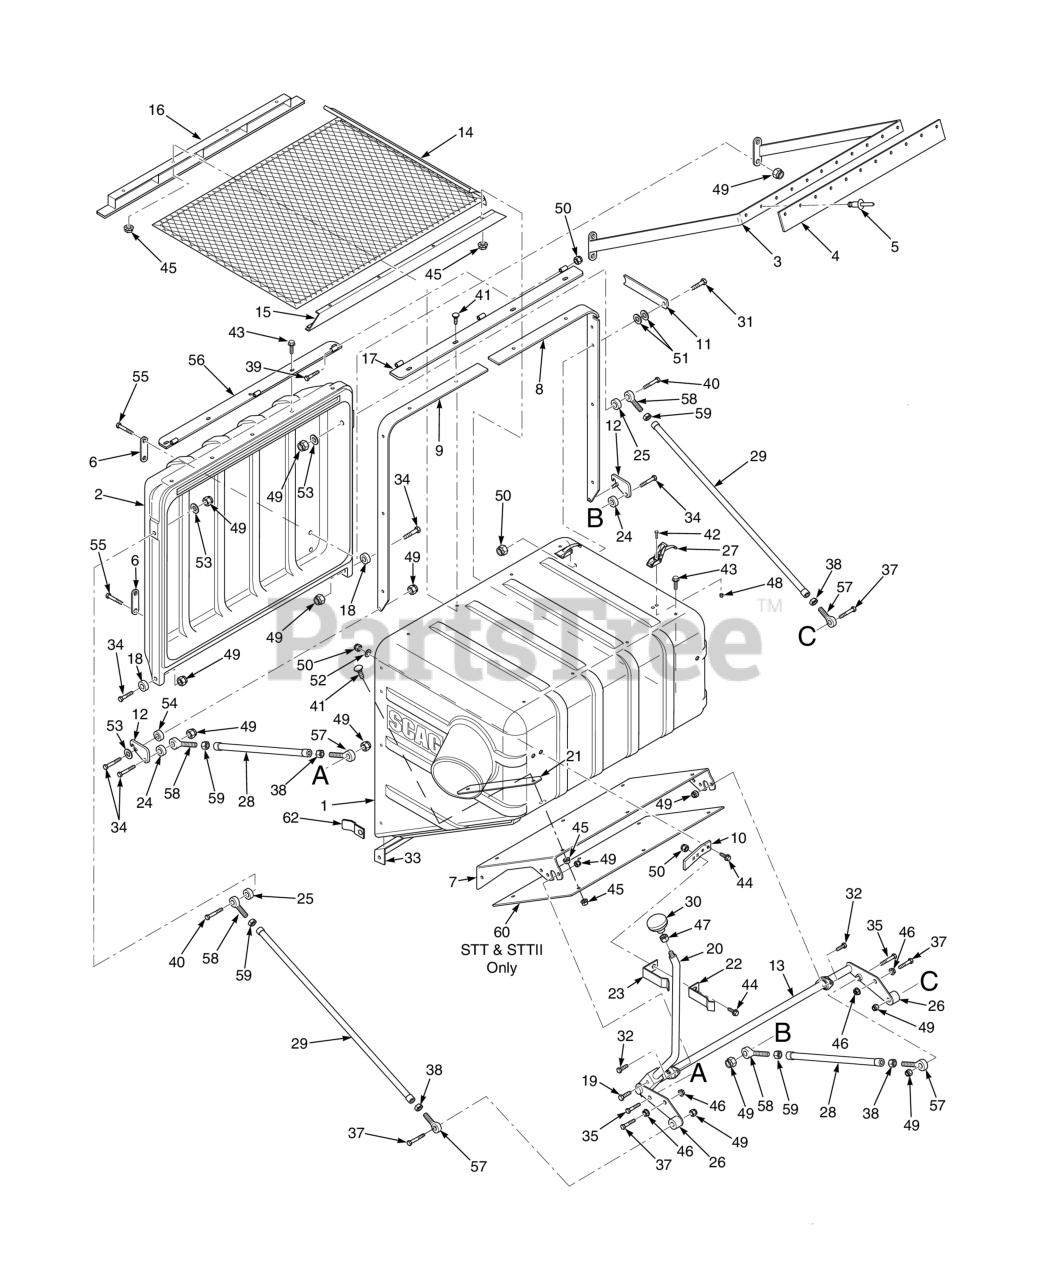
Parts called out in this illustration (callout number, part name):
1	Hopper, GC-STT-CS
2	Door, GC-CS
3	Sweeper Weldment, GC-CS
4	Pad, Rubber
5	Pop Rivet, 3/16 x .652"
6	Plate, Stiffener
7	Support Frame, Hopper
8	Hinge Bracket, L.H.
9	Hinge Bracket, R.H.
10	Mounting Bracket, Dump Handle Latch
11	Latch, Door Prop
12	Plate, Latch
13	Bellcrank Weldment, Upper
14	Debris Screen Weldment
15	Screen Support Weldment, Rear
16	Screen Support Weldment, Front
17	Hinge Weldment, Hopper
18	Spacer, Idler Bearing
19	Bolt, Hex Head 5/16-18 x 1-1/2" - Front
20	Rod, Dump Lever GC-SCZ-CS
21	Retainer Strip, Hopper
22	Latch, Dump Rod Inner
23	Latch, Dump Rod Outer
24	SPACER, IDLER
25	SPACER, J PULL ROD
26	SPACER, J-PULL ROD
27	LATCH, HOOD
28	Linkage Assembly, Lower
29	Linkage Assembly, Upper
30	Knob, Cutter Deck Release
31	Bolt, 5/16 - 18 x 1 - 1/4" Hex Head
32	Bolt, Hex Head, 3/8-16 x 3/4"
33	Bracket, Lower Stiffener
34	Bolt, Hex Head 3/8-16 x 1-1/2" B&S 32BV
35	Bolt, Hex Head 3/8-16 x 1-3/4" (Kohler EFI)
36	Alignment Bracket, GC-CS
37	Capscrew, Hex Head 3/8-16 x 2.0"
38	Nut, 3/8-24 UNF R.H. Thread
39	Bolt, Hex Head 5/16-18 x 3-1/2"
40	Bolt, Hex Head, 3/8-16 x 3-1/2"
41	Bolt, Carriage 5/16-18x1" (large frame units only)
42	SCREW, PHILLIPS WASHER HEAD #10-32 X 1/2"
43	Capscrew, 5/16-18 x .75 Serrated Flange Hex Head
44	Cpscrw, 5/16-18 x 1"Serrated Flange Hex Head
45	Nut, Serrated Flange 5/16-18 (Right Front Engine Mounting, Briggs and Kohler Only)
46	NUT, 3/8-16 SERRATED FLANGE HEX HEAD
47	Nut, Jam 3/8-16
48	HEX NUT, ELASTIC STOP LOCK # 10-32
49	HEX NUT, ELASTIC STOP LOCK, 3/8-16
50	HEX NUT, ELASTIC STOP LOCK, 5/16-18
51	Socket Head Capscrew #8-32 x 1/2"
52	Flatwasher, 5/16-.375 x .875 x .083 (35BV & 37BV-EFI)
53	Flatwasher, 3/8" Special (.391 x .938 x .105)
54	Bushing, Hopper Latch GC-CS
55	Bolt, Hex Head 3/8-16 x 3" - 52"
56	Hinge Weldment, Door
57	Rod End Male, 3/8-24 R.H. Thread
58	Rod End Male, 3/8-24 L.H. Thread
59	Nut, 3/8-24 UNF-2B LH Thread
60	Heat Shield, GC-STT Only
